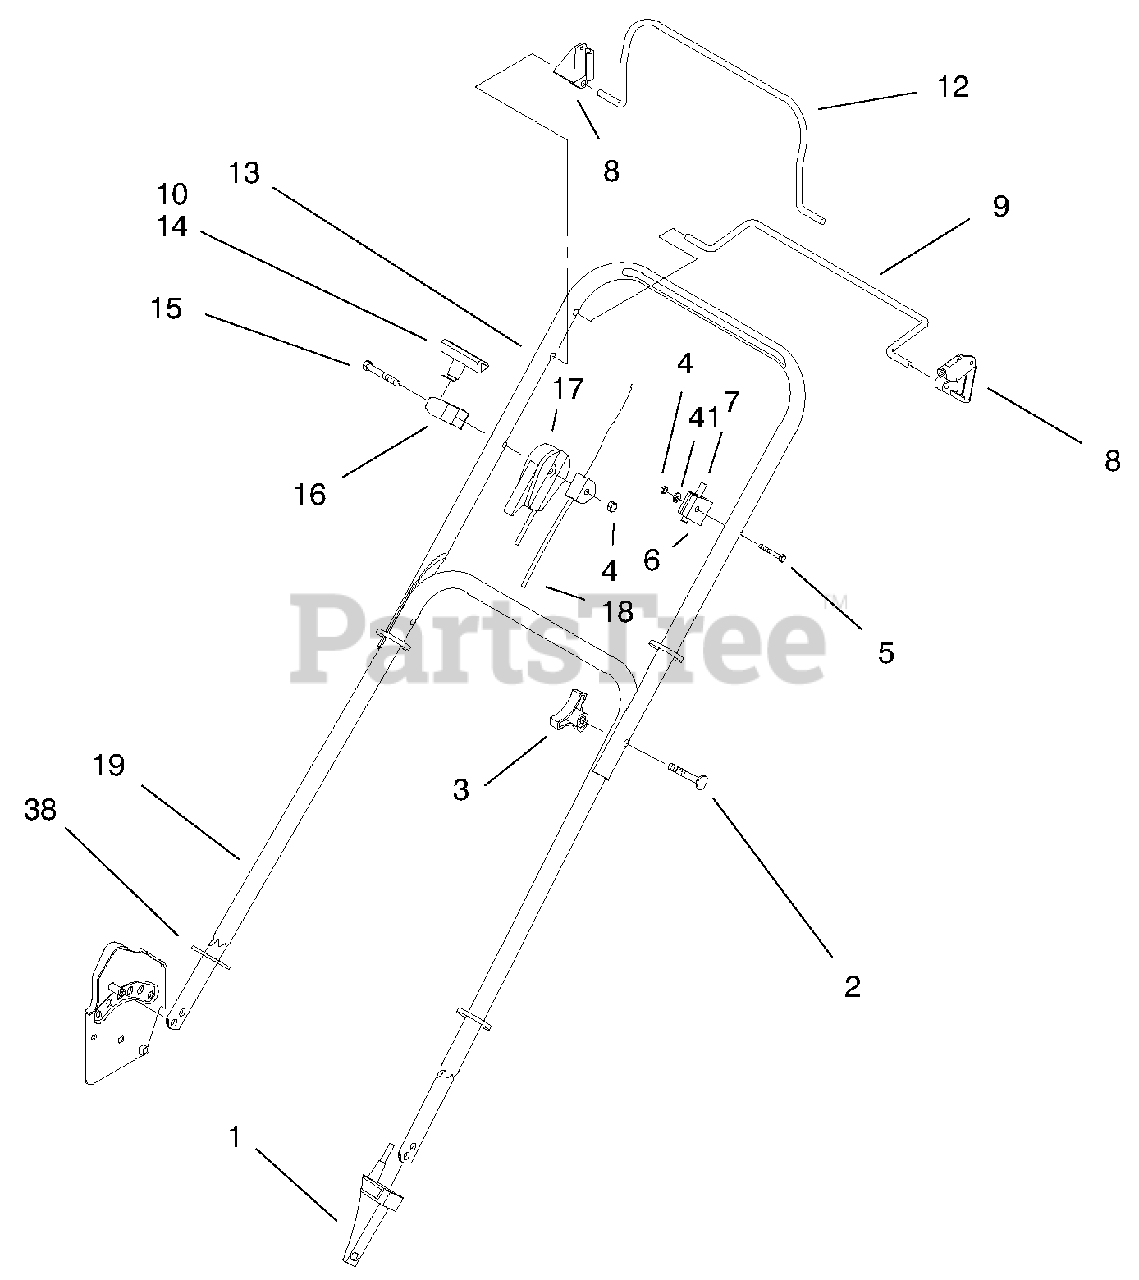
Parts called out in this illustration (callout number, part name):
1	Anchor-Cable
2	Screw-Handle
3	Knob
4	Nut-Lock
5	Screw-Handle
6	Anchor-Cable
7	Cable-Traction
8	Stop-Pivot
9	Bail-Sp Control
10	Staple-Handle
12	Bail-Flywheel Brake
13	Handle Section-Upper
14	Handle-Starter
15	Screw-HH
16	Guide-Rope
17	Cable-Throttle
18	ASM-Brake Cable
19	Handle Section-Lower
38	Handle-Guard
41	Washer-Flat
